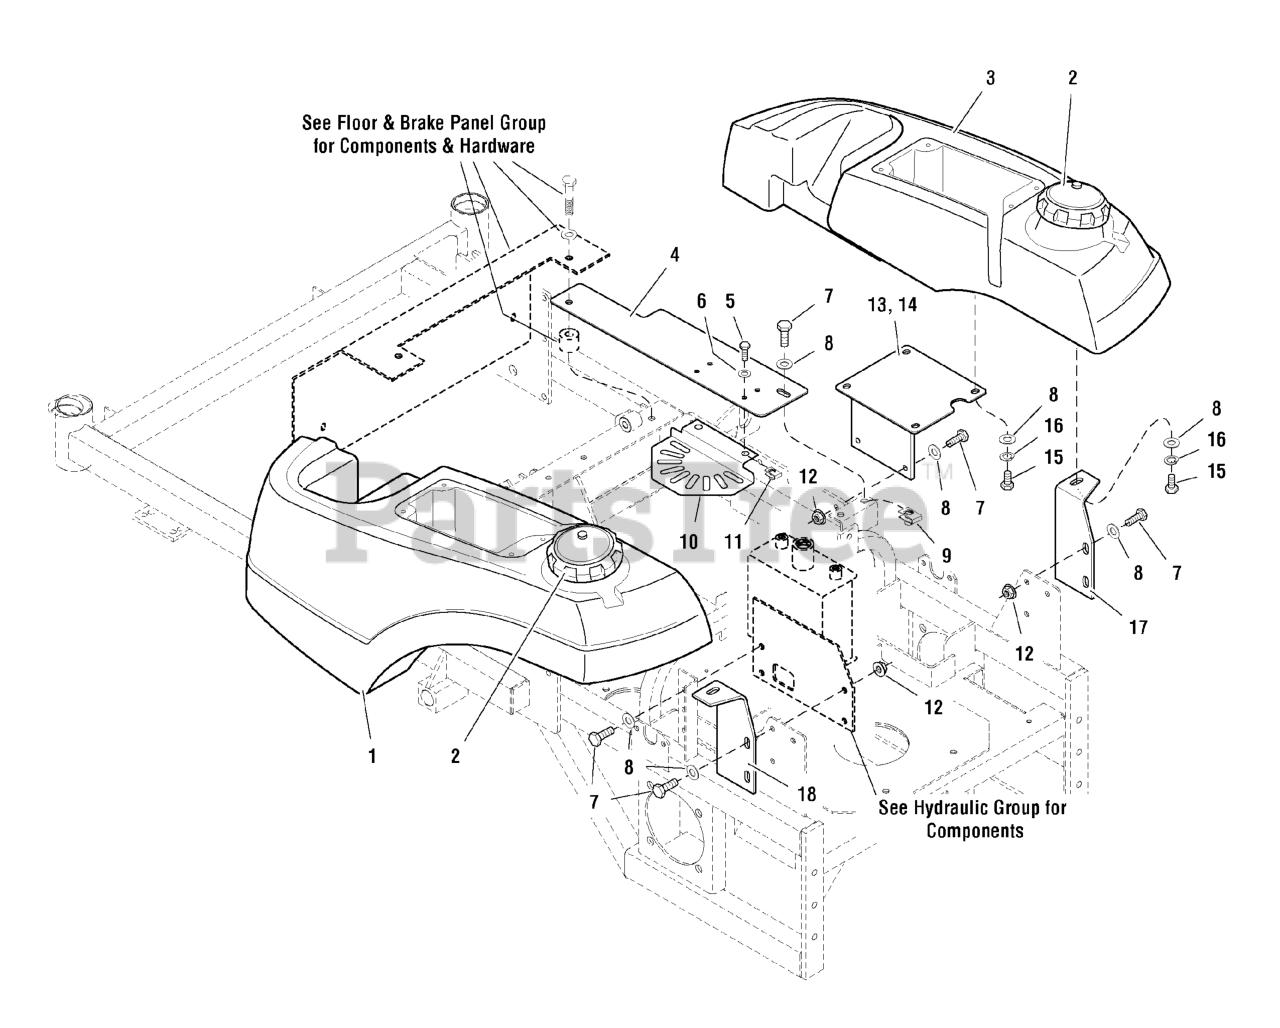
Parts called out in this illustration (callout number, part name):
1	FUEL TANK, 1000Z, LH
1	Filler Neck
2	CAP, FUEL TANK, 3-1/2 NECK
3	FUEL TANK, 1000Z, RH
3	Filler Neck
4	COVER, Fan Shield Mount
5	BOLT, 1/4-20 x 3/4
6	WASHER, 1/4 SAE
7	BOLT, 5/16-18 X 1 GD5 YZ
8	WASHER, 5/16" SAE
9	BODY CLIP, 5/16-18-7GA MATERIAL
10	FAN SHIELD
11	BODY CLIP, 1/4-20
12	NUT, 5/16-18 HEX SERRATED FLANGE (SMALL)
13	FUEL TANK MOUNT-RH
14	FUEL TANK MOUNT-LH
15	BOLT, 5/16-18 X 3/4 GD5
16	WASHER, 5/16 LOCK CZ
17	BRACKET, Fuel Tank Support-RH
18	BRACKET, Fuel Tank Support-LH
